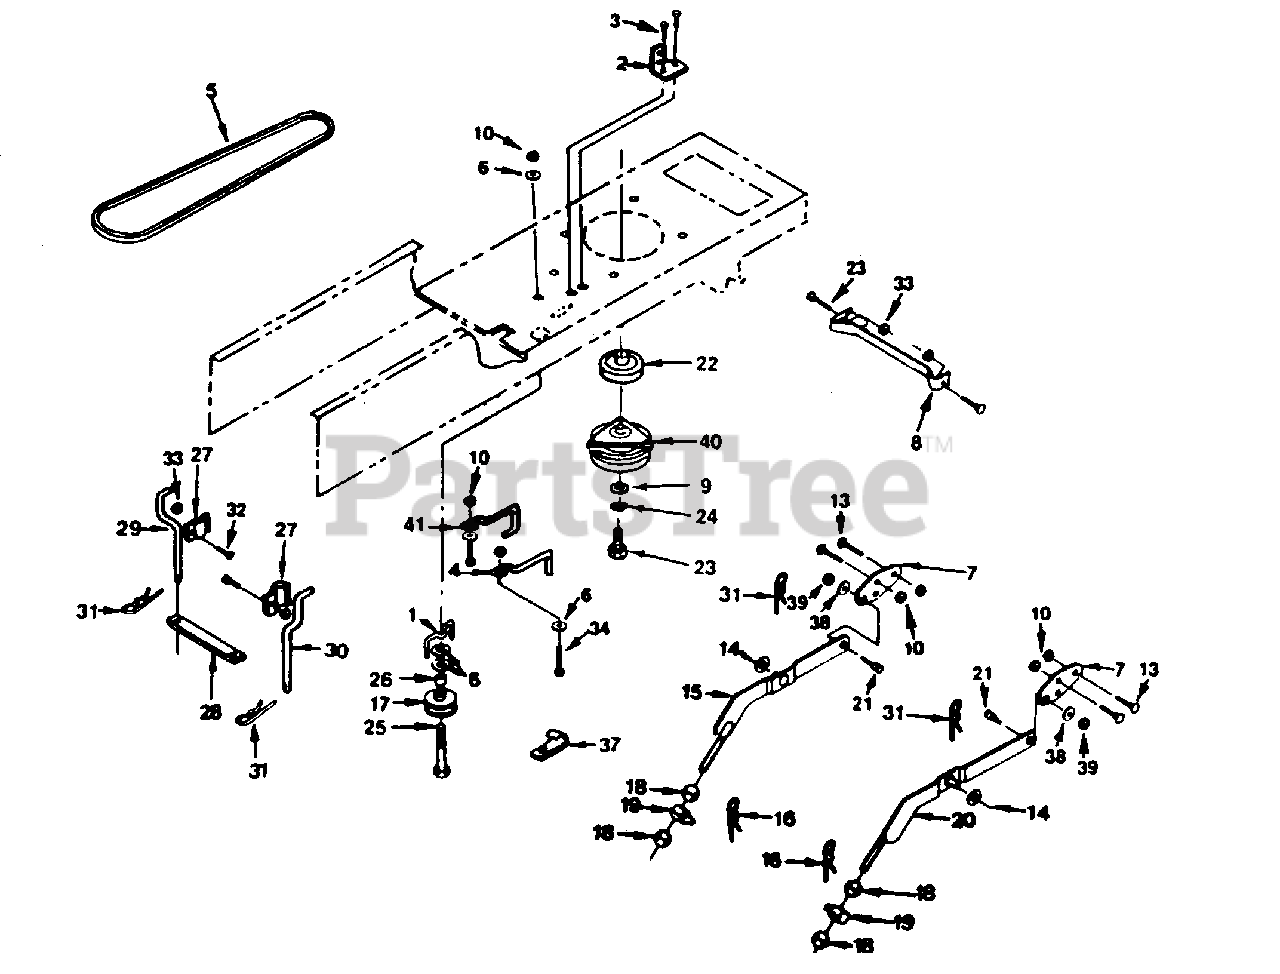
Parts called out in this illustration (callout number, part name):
1	Belt Keeper (AYP part number)
2	Switch Bracket (AYP part number)
3	Tapping Hex Screw (AYP part number)
4	R.H. Engine Belt Keeper (AYP part number)
5	Drive V-Belt (AYP part number)
6	Washer (AYP part number)
7	Suspension Bracket (AYP part number)
8	Clutch Retainer (AYP part number)
9	Washer (AYP part number)
10	Crownlock Nut
12	Hex Bolt 7/16-20 x 4 (AYP part number)
13	Sq. Neck Round Hd. Bolt (AYP part number)
14	Washer (AYP part number)
15	L.H. Suspension Arm Assembly (AYP part number)
16	Spring Retainer (AYP part number)
17	Flat Idler (AYP part number)
18	Hex Nut 1/2-13 (AYP part number)
19	Lower Lift Trunnion (AYP part number)
20	R.H. Suspension Arm Assembly (AYP part number)
21	Shoulder Bolt (AYP part number)
22	Engine Pulley (AYP part number)
23	Carriage Bolt
24	Lock Washer (AYP part number)
25	Hex Bolt 3/8-16 x 2-3/4 (AYP part number)
26	Spacer (AYP part number)
27	Clamp (AYP part number)
28	Locater Strap (AYP part number)
29	L.H. Belt Keeper (AYP part number)
30	R.H. Belt Keeper (AYP part number)
31	Retainer Spring (AYP part number)
32	Hex Bolt 5/16-18 x 3/4 (AYP part number)
33	Locknut
34	Hex Bolt 3/8-16 x 1 (AYP part number)
38	Spring Washer (AYP part number)
39	Flange Locknut (AYP part number)
40	El??c??tric Clutch (AYP part number)
41	L.H. Engine Belt Keeper (AYP part number)
